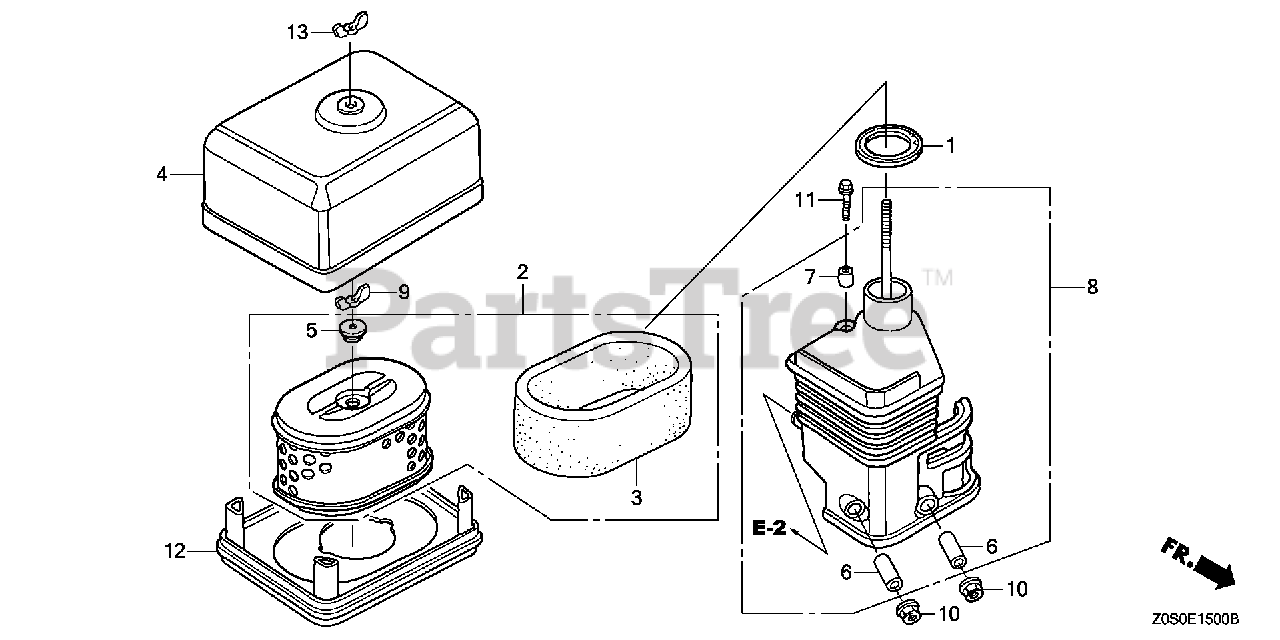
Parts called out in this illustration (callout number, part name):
1	GASKET, ELBOW
2	ELEMENT, AIR CLEANER (DUAL)
3	FILTER (OUTER)
4	COVER, AIR CLEANER
5	GROMMET, AIR CLEANER
6	COLLAR, AIR CLEANER Use from Engine SN 1786085.
7	COLLAR B, AIR CLEANER
8	ELBOW, AIR CLEANER
9	WINGNUT, TOOL BOX SETTING
10	NUT, FLANGE (6MM)
11	BOLT, FLANGE (6X20)
12	NOSE, MUFFLER
13	NUT, AIR CLEANER
